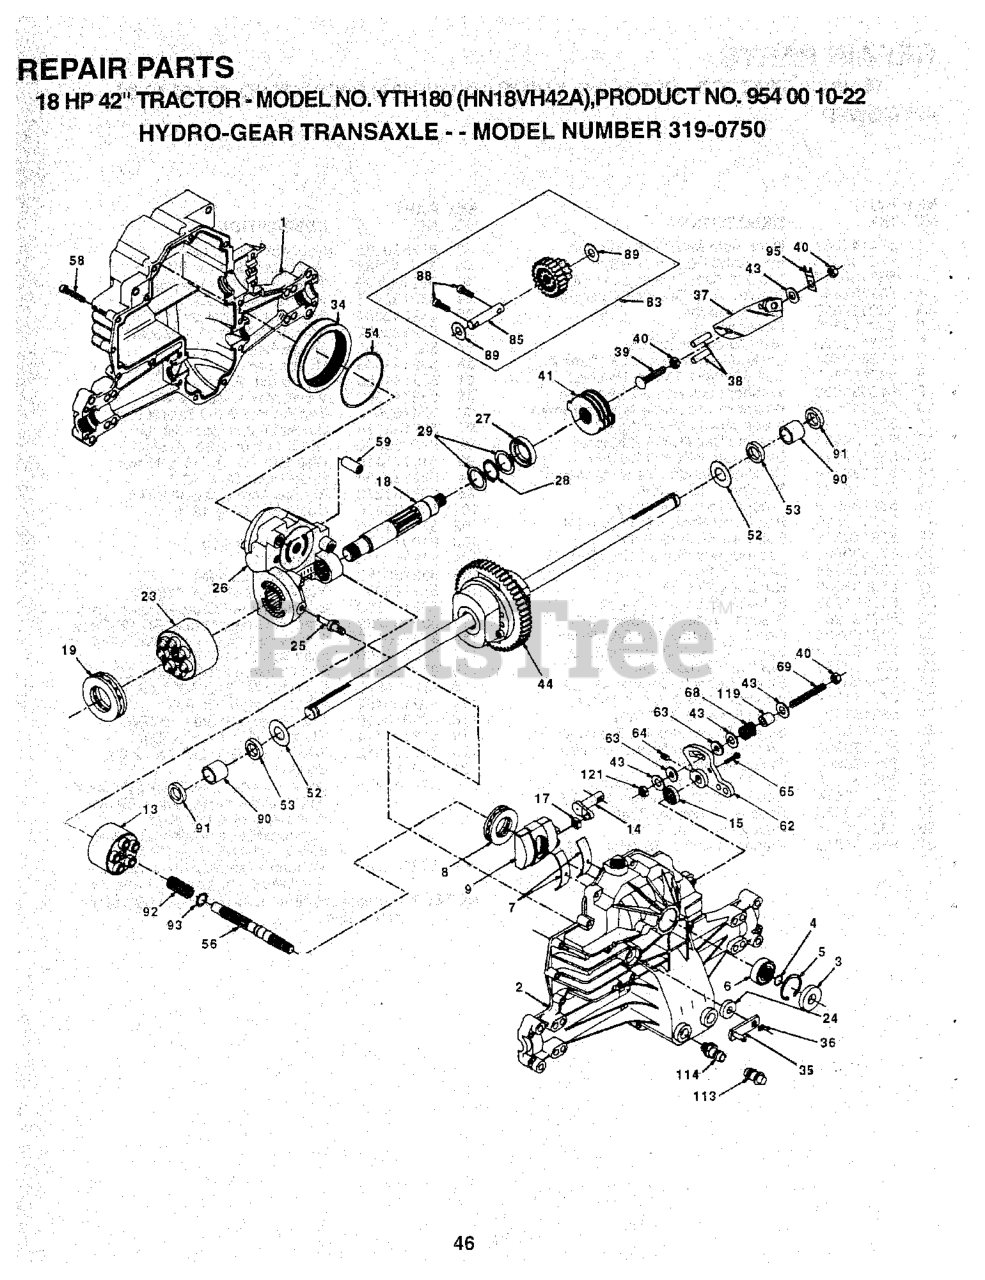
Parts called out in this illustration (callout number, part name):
1	LOWER HOUSING
2	HOUSING UPPER 70255
3	SEAL.LIP.H-G.(9008000-0128)
4	RING RETAINING 2003016
5	RING.RETAINING.(2003052)
6	BALL BEARING
7	CRADLE BEARING
8	THRUST BEARING
9	SWASHPLATE (2003087)
13	BLOCK, CYL ASSY
14	TRUNNION ARM
17	SLOT GUIDE
18	MOTOR SHAFT
19	THRUST BEARING
23	BLOCK, CYL ASSY
25	BYPASS ACTUATOR
26	CENTER SECTION ASSY KIT
28	RETAINING RING
34	ELEMENT, OIL FILTER
35	BYPASS ARM
36	RETAINING RING 44870
37	ACTUATING ARM
38	ACTUATING PIN 44891
40	NUT.LOCK.HX.(H-G PART 50108)
41	BRAKE ROTOR 70135 HYDRO-GEAR
43	WASHER .34X.88X.06.44130
52	WASHER.HYDRO GEAR.50152
53	SEAL.HYDRO.53901
56	SHAFT.INPUT.50005
58	BOLT #44876
62	CONTROL ARM 50254
63	DAMPENER PUCK
64	SCREW.SET.50018
68	SPRING HELICAL COMP 50277
69	SCREW
83	JACK SHAFT ASSY
85	JACK SHAFT
89	WASHER 50132
90	SLEEVE.BEARING 50118
92	SPRING 2003014
95	STRAP, LOCKING
113	CAP, VENT ASSY
114	O-RING KIT 70110
119	SPACER.HYDRO GEAR 50278
121	NUT
